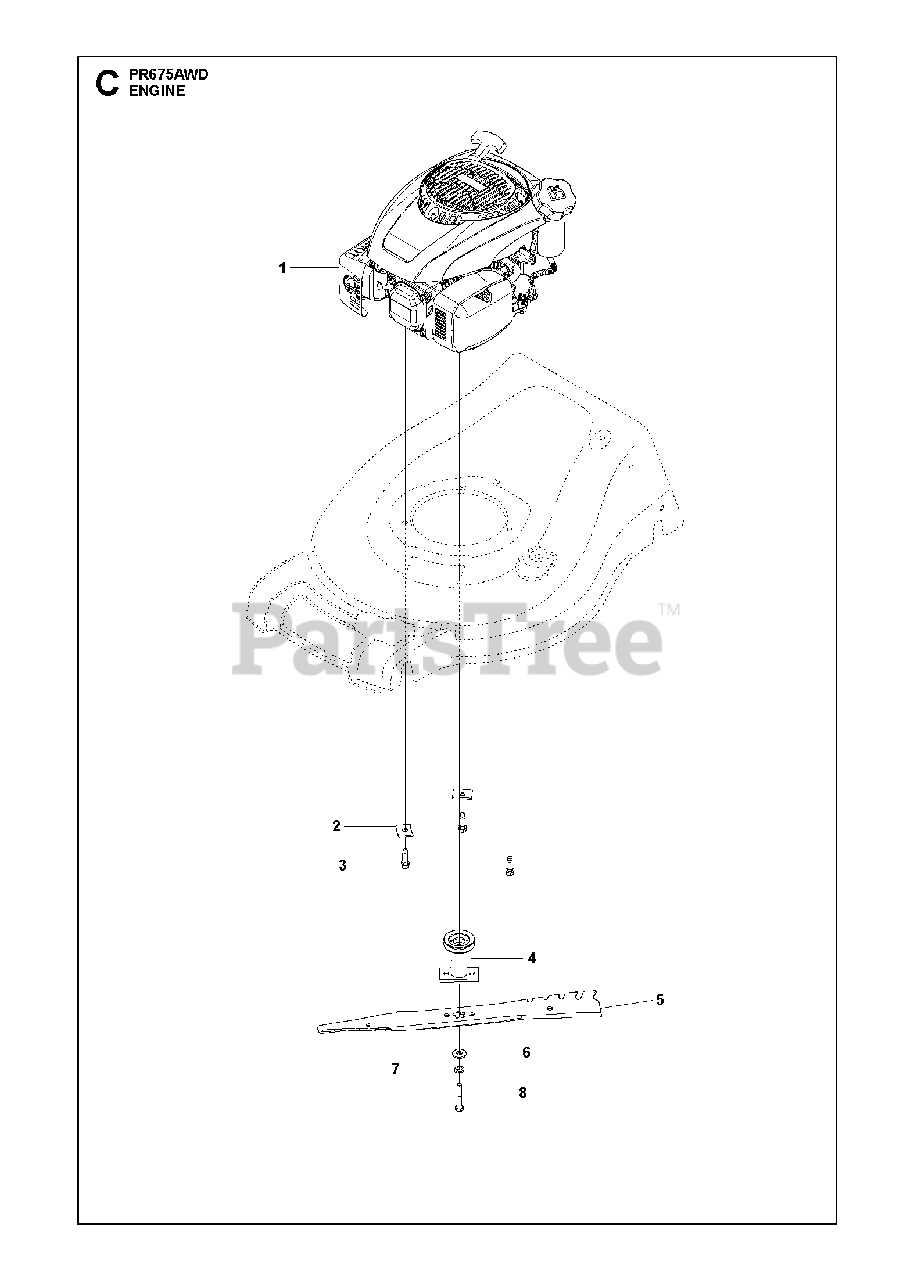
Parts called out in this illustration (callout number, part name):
2	WASHER.ENGINE.BZP
3	BOLT 3/8-16X1-1/8
4	ADAPTER.BLADE.25M.21EFF.AW/RW
5	Mower Blade, 21" Reaper without Notches
6	WASHER,HARDEN
8	Engine Pulley Bolt
